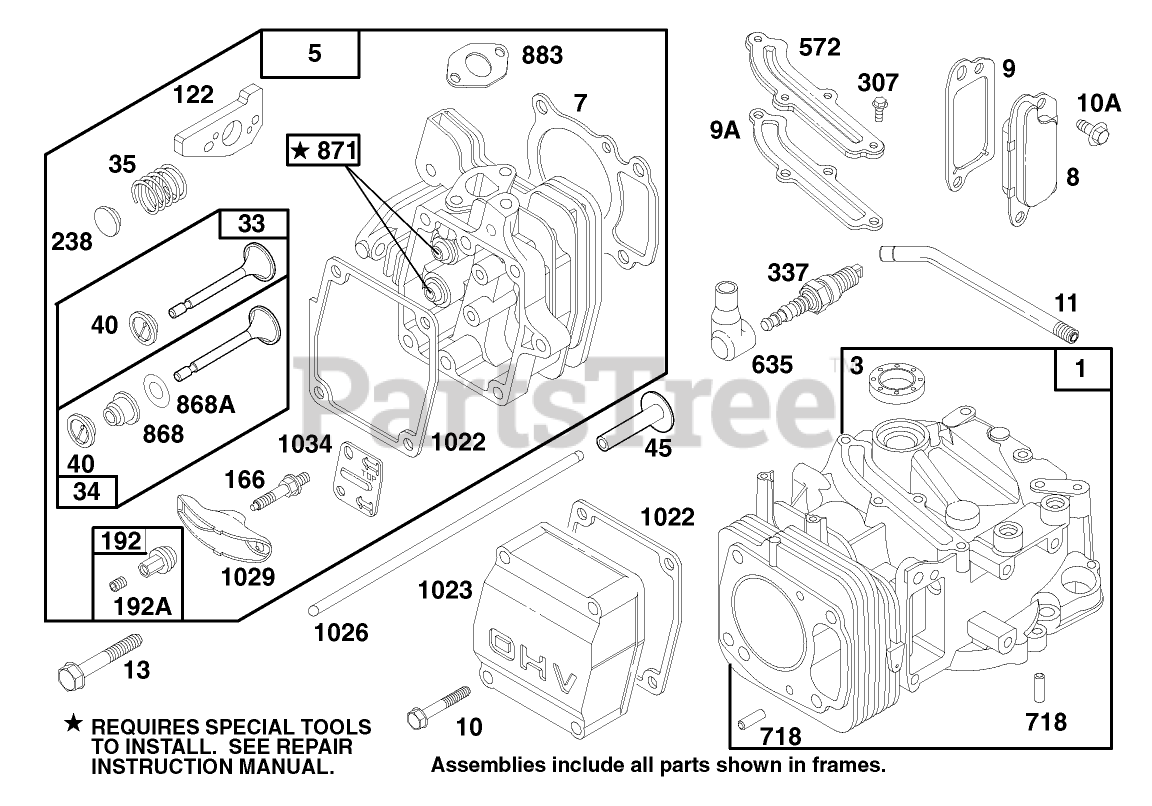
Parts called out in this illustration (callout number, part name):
95	SCREW - ROUND HEAD
98	IDLE ADJUSTING SCREW
104	FLOAT HINGE PIN
108	VALVE - CHOKE
116	SEALING GASKET
117	Jet-Main
118	VALVE/SPRING - NEEDLE
122	ADAPTER ASSEMBLY
124	HEX HEAD SCREW
125	ASSEMBLY - CARBURETOR
127	PLUG - WELCH
130	THROTTLE VALVE
131	THROTTLE SHAFT
133	FLOAT-CARBURETOR
134	Valve-Inlet (Includes Seat)
136	FLOAT BOWL
137	FLOAT BOWL GASKET
141	CHOKE SHAFT
147	JET - PILOT
634	SEAL WASHER
955	HEX HEAD SCREW
975	CARBURETOR BOWL ASM
1011	VENT TUBE
1039	FLOAT LIMITER
1091	CAP - LIMITER
